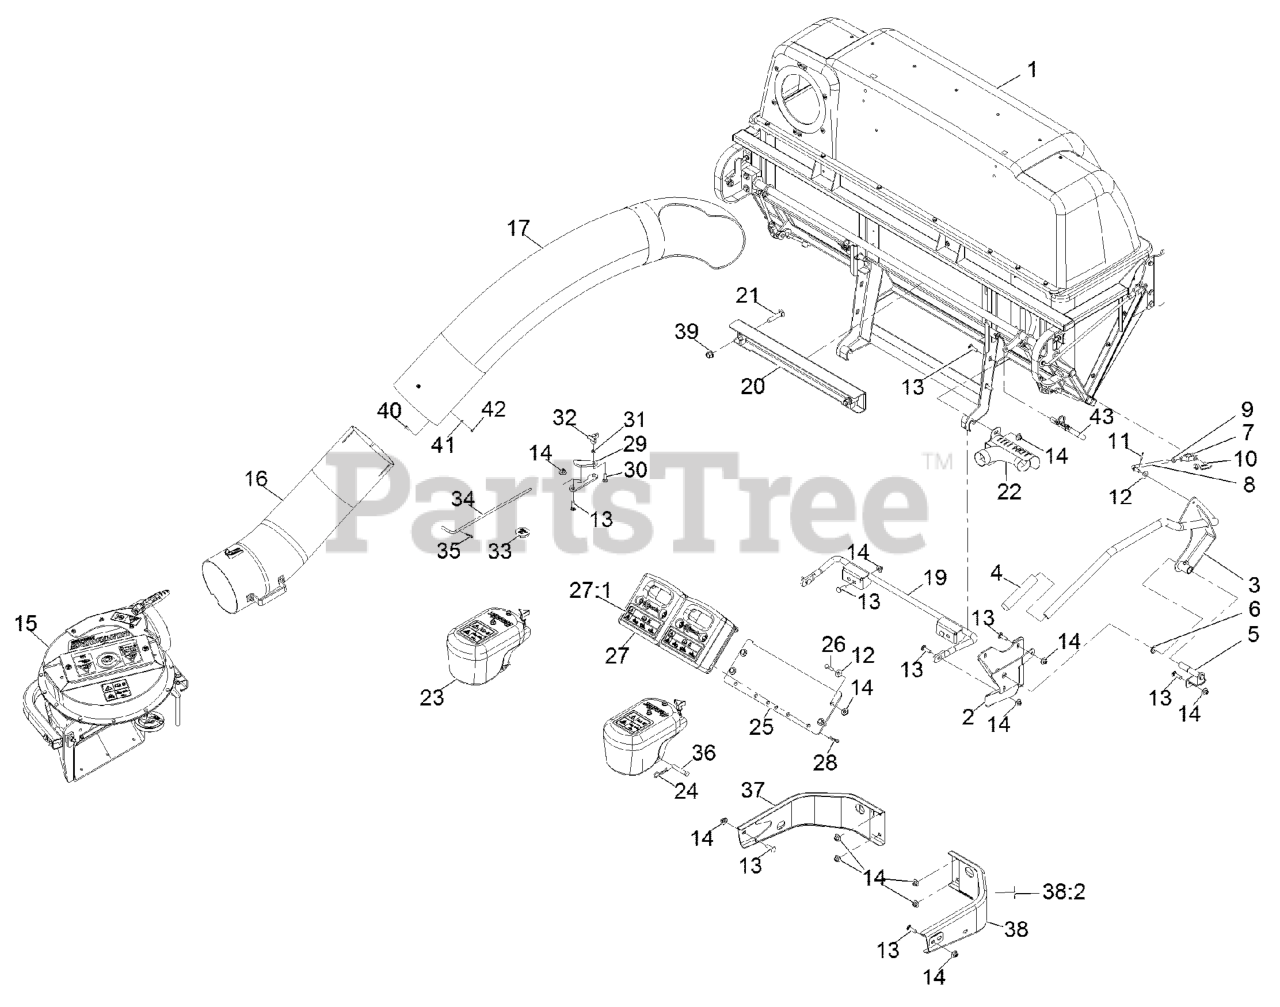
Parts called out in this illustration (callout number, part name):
1	ASM,Hopper Lg Qds
2	MOUNT-PIVOT
3	WLD,DUMP HANDLE
4	HANDLE-GRIP
5	PIN-HANDLE
7	YOKE-LINKAGE, BRAKE
8	LINK-HANDLE
9	NUT-HEX
10	PIN-SPRING, CLEVIS
11	PIN-COTTER
12	WASHER-FLAT
13	Bolt-Carriage 3/8-16 X 1 1/4
14	Nut-Nyloc 3/8-16 Flg
15	ASM, BLOWER LARGE - SVC O
16	LOWER TUBE ASM
17	TUBE-UPPER
19	MOUNT-BAGGER, LOWER
20	MOUNT-BAGGER, UPPER
21	SCREW-CARR
22	EXHAUST DIVERTER ASM
23	ASM,CASTER WEIGHT
24	PIN-COTTER
25	PLATE,WEIGHT ASM MOUNT
26	SCREW-HH
27	ASM,CAST WEIGHT
27:1	DECAL-WARNING WEIGHT
28	PIN-HAIR
29	BRACKET,BELT COVER
30	BOLT-CARR
31	RING-RETAINING, BOLT
32	KNOB-3 PRONG
33	PLUG, BLACK NYLON 1.75
34	PIN,CHUTE PIVOT
35	PIN-COTTER
36	PIN-CLEVIS
37	BUMPER-RH
38	LH BUMPER ASM
38:2	DECAL-WARNING
39	Nut-Lock 1/2-13
40	SCREW-HWH
41	WASHER-FLAT
42	NUT-LOCK, NI
43	PIN-MOUNT, BAGGER
